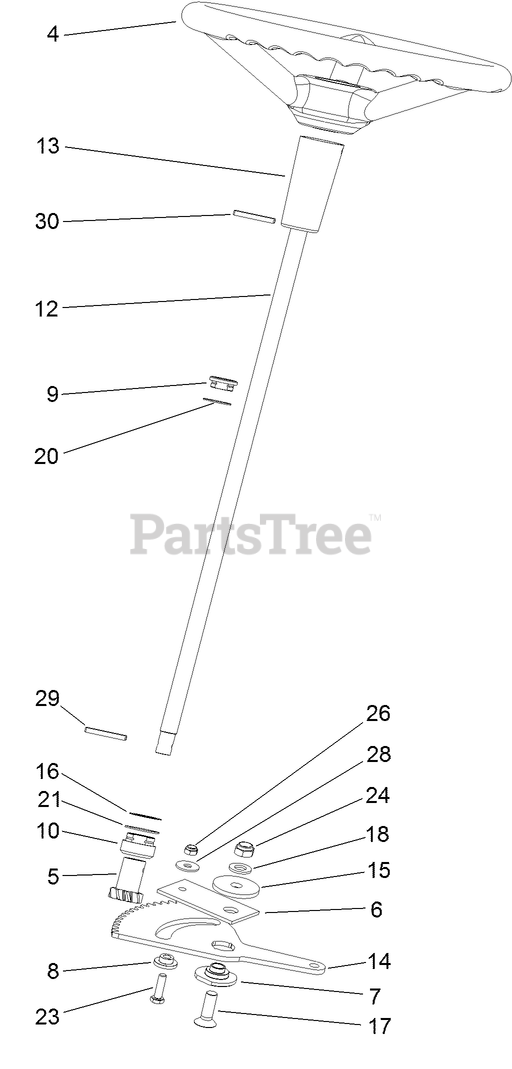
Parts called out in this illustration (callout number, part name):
4	WHEEL-STEERING
5	PINION-STEERING
6	PLATE-STEERING
7	PIVOT-STEERING
8	BUSHING-SECTOR
9	BEARING
10	BUSHING-PINION
12	SHAFT-STEERING
14	GEAR-SECTOR
15	WASHER
16	WASHER
18	WASHER-FLAT
20	RING-LOCKING
21	RING-LOCKING
23	SCREW-HH
24	NUT-HEX
26	NUT-LOCK, NI
28	WASHER-PLAIN
29	PIN-SPIRAL
30	PIN-SPIROL
